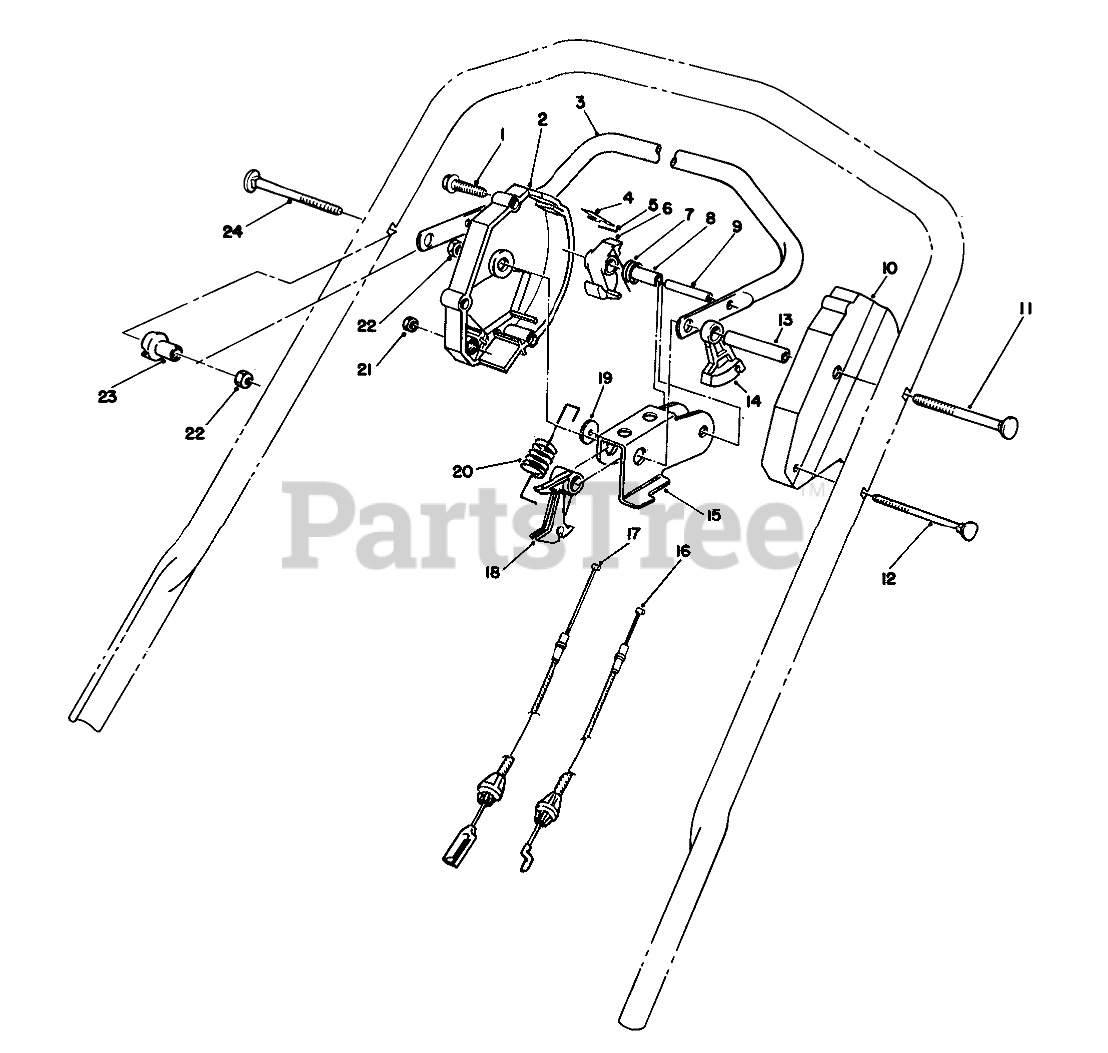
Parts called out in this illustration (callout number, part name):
1	SCREW-HWHTF
2	Housing-Control
3	Bar-Control
4	SPRING-LEAF
5	PIN-INSERT
6	HOOK-CONTROL
7	SPRING-TORSION
8	SPACER
9	PIN-ROLL, SLOTTED
10	HOUSING-CONTROL, LH
11	Screw-Handle
12	HANDLE SCREW
13	TUBING-SPACER
14	LEVER-TRACTION
15	ROCKER
16	Cable-Traction
17	Cable-BBC
18	LEVER-CABLE
19	WASHER-NYLON
20	SPRING-DETENT
21	NUT-HEX
22	NUT-LOCK, NI
23	SPACER-SUPPORT
24	SCREW-HANDLE
